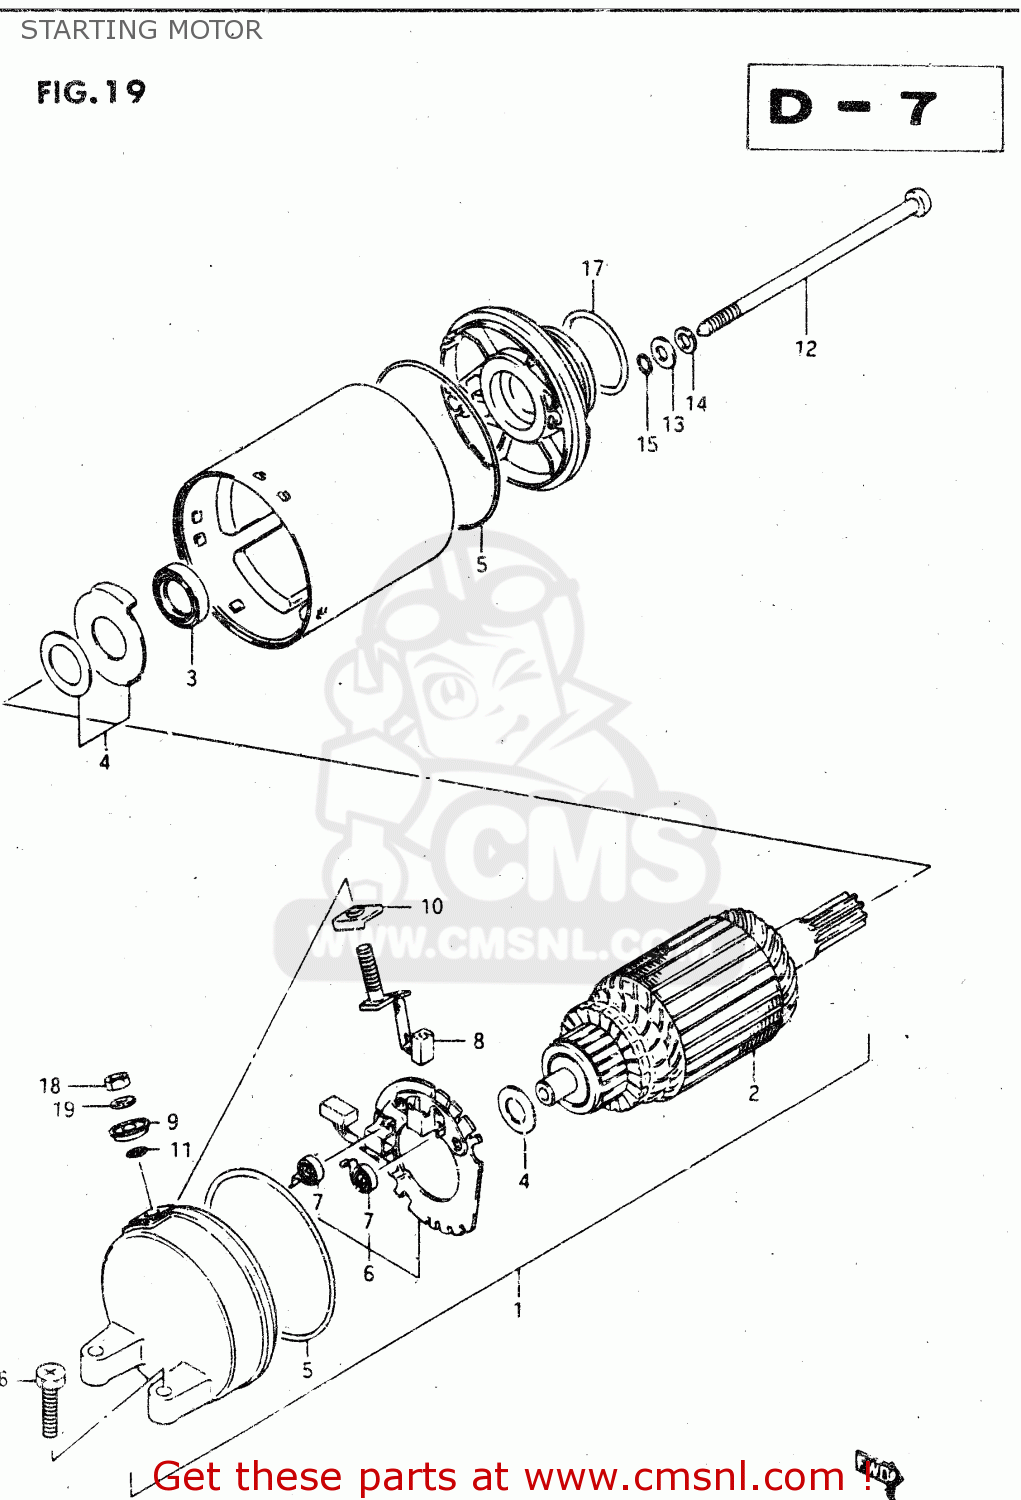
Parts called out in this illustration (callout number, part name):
1	MOTOR ASSEMBLY,STARTING
2	ARMATURE
3	SEAL,OIL
4	SHIM SET,STARTING MOTOR
5	O RING
6	HOLDER,BRUSH
7	SPRING
8	BRUSH SUB ASSY,STARTING MOTOR
9	BUSHING
10	BUSH,B
11	O RING
12	BOLT
13	WASHER
14	WASHER,LOCK
15	O RING
16	SCREW (6X25)
17	O RING(D:3,ID:24.5)
18	NUT
19	WASHER,LOCK
